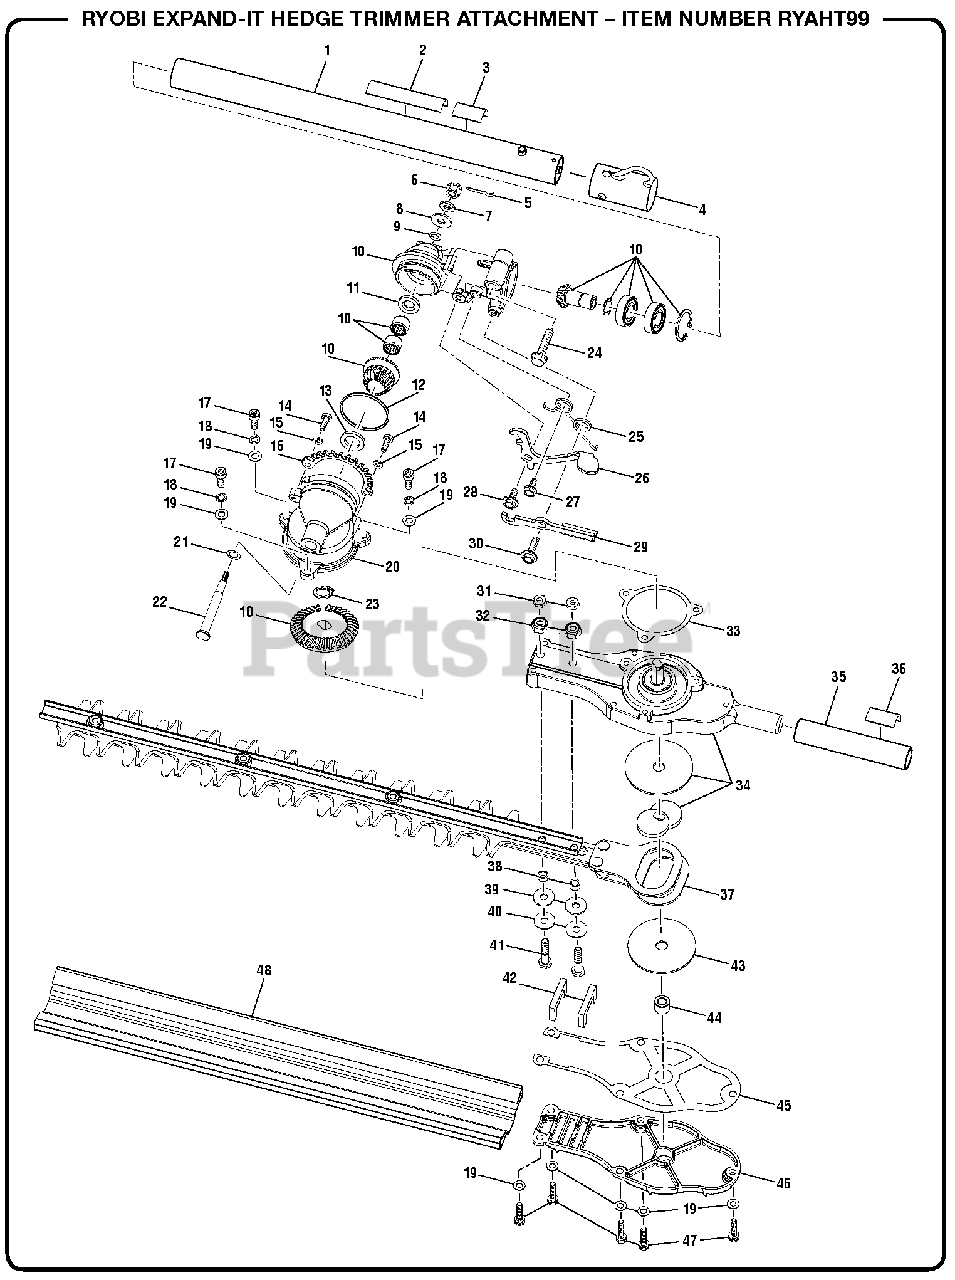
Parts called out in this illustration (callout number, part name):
1	Lower Drive Shaft Assembly
2	Warning Label
3	Logo Label
4	Hanger Cap
5	Cotter Pin
6	Castle Nut
7	Spring Washer
10	Gear Assembly
15	Spring Washer
16	Ratchet Wheel
17	Bolt (M5 x 14 mm)
18	Lock Washer (5 mm)
19	Washer (OD9.8 x ID5.3 x 0.8t)
20	Gear Case
21	Paper Seal
24	Screw (1/4-20 x 1-1/4 in.)
25	Torsion Spring
26	Adjustment Spring
27	Screw (10-24 x 7/16 in. T.F.)
28	Screw (M5 x 8.5 mm, Hex. Hd.)
29	Lock Cover
30	Screw (M5 x 15 mm, Hex. Hd.)
31	Hex Nut (M6)
32	Lock Nut (M6)
34	Gear Case
35	Handle
36	Hot Surface Label
37	Blade Assembly
39	Washer (OD16 x ID6.8 x 1.5t)
40	Washer (Bellville)
41	Bolt (M6 x 32 mm, Hex Hd.)
42	Felt Seal
43	Blade Washer
46	Gear Box Cover
47	Screw (M5 x 22.8 mm)
